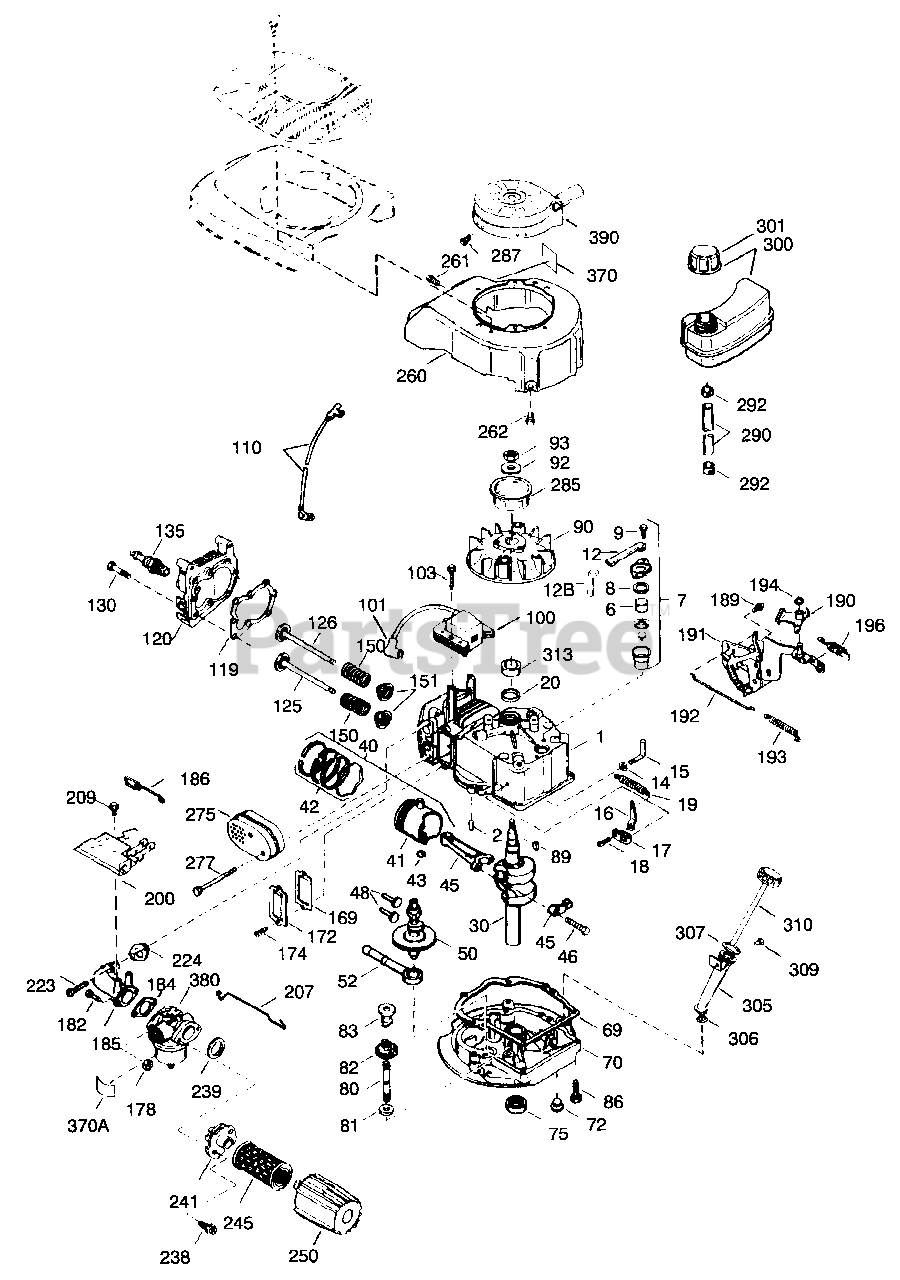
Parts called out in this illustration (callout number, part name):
1	Cylinder (Incl. Ref. #2 &20)
2	Pin-Dowel
6	Element-Element
8	Gasket-Breather
12	Tube-Breather
12B	Elbow-Breather Tube
14	Washer-Flat
15	Rod-Governor
16	A Lever-Governor
17	Clamp-Governor Lever
19	Spring-Extension
20	Seal-oil
30	Crankshaft
40	Set-Piston, Pin & Ring (Std)
41	Piston & Pin Assembly (Std. Incl. Ref. #43)
42	Set-Rings (Std)
43	Retainer-Piston Pin
45	Rod-Connecting (Incl. Ref. #46)
46	Bolt-Connecting Rod
48	Lifter-Valve
50	Camshaft
52	Oil Pump Assembly
70	Flange-Mtg. (Incl. Ref. #72,75,80,82,83,311 & 312)
72	Plug-Oil
75	Seal-Oil
80	Shaft-Governor
81	Washer-Flat
82	Governor Shaft Assembly
83	Spool-Governor
89	Key-Flywheel
90	Flywheel
92	Washer-Belleville
93	Nut-Flywheel
100	Solid State
101	Cover-Spark Plug
110	Wire-Ground
119	Gasket-Cylinder Head
120	Head-Cylinder
125	Valve-Exhaust (1 /32 O.S Incl. Ref. #151)
126	Valve-Intake (1/32 O.S Incl. Ref. #151)
135	Spark Plug (RJ19LM)
150	Spring-Valve
151	Cap-Valve Spring
169	Gasket-Valve Spring
172	Cover-Valve Spring
178	Nut/Washer
182	Screw
184	Gasket-Carburetor
185	Pipe-Intake (Incl. Ref. #224)
186	Link-Governor Spring
190	Lever-Brake
191	Bracket-Brake
192	Link-Control
193	Spring-Brake
194	ring-Retaining
195	Terminal
200	Control Bracket Assembly
207	Link-Throttle
224	Gasket-Intake Pipe
239	Gasket-Air Cleaner
241	Collar-Air Cleaner
245	Filter-Air Cleaner
250	Cover-Air Cleaner
260	Housing-Blower
275	Muffler (Incl. Ref. #277)
285	Hub-Starter
290	Line-Fuel
292	Clamp-Fuel Line
300	Tank-Fuel (Incl. Ref. #292 & 301)
301	Cap-Fuel
305	Tube Fill
306	"O"Ring
307	"O"Ring
310	Dipstick
313	Spacer-Flywheel
370	Decal-Instructions
370A	Decal-Primer
380	Carburetor (Incl. Ref. #184)
390	Starter-Recoil
